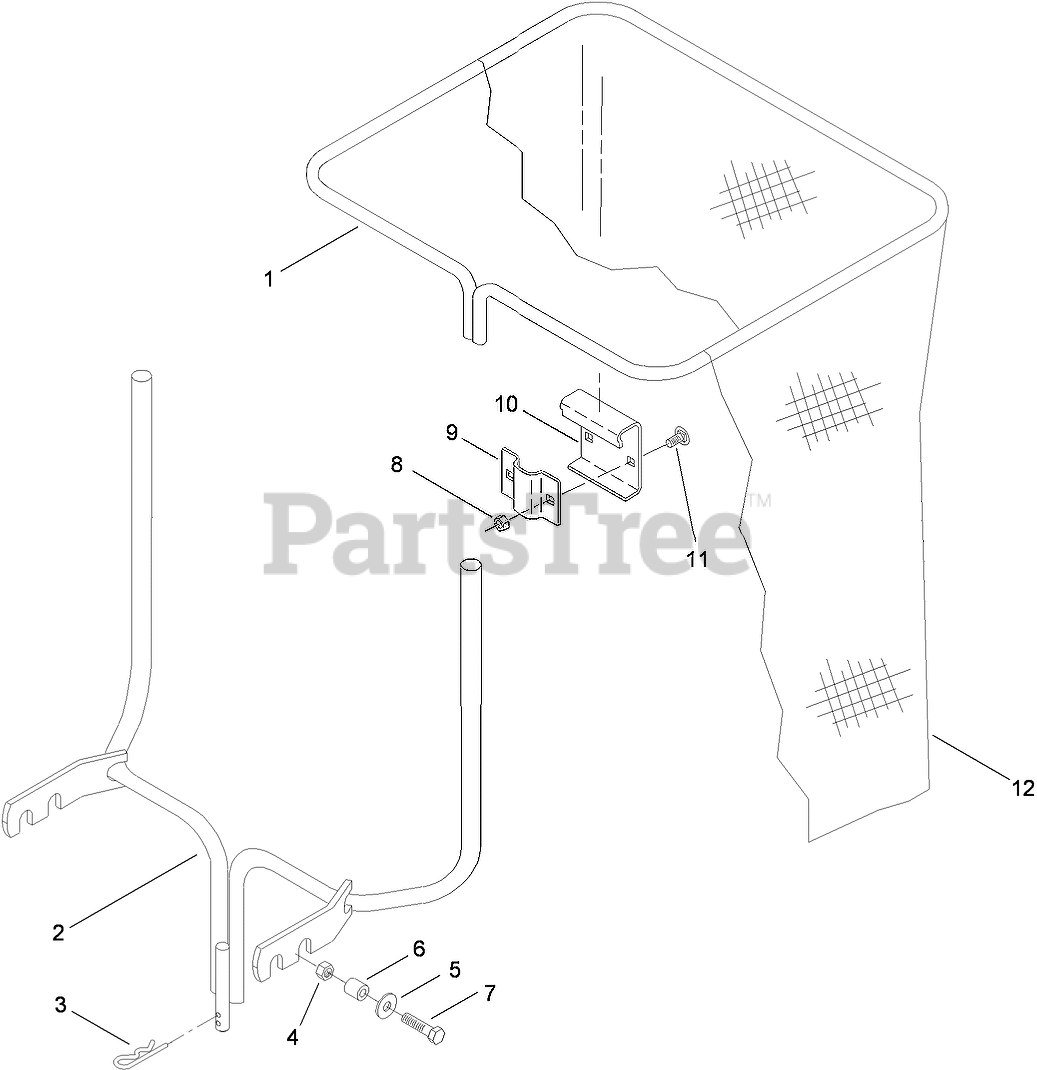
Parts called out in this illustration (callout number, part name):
1	FRAME-BAG
2	BRACKET-BAGGER ASM
3	PIN-COTTER, HAIR
4	NUT-LOCK, NI
5	Washer
6	SPACER
7	SCREW-HH
8	NUT-LOCK, NI
10	HANGER-BAG
11	BOLT-CARR
12	BAG-DEPTH
